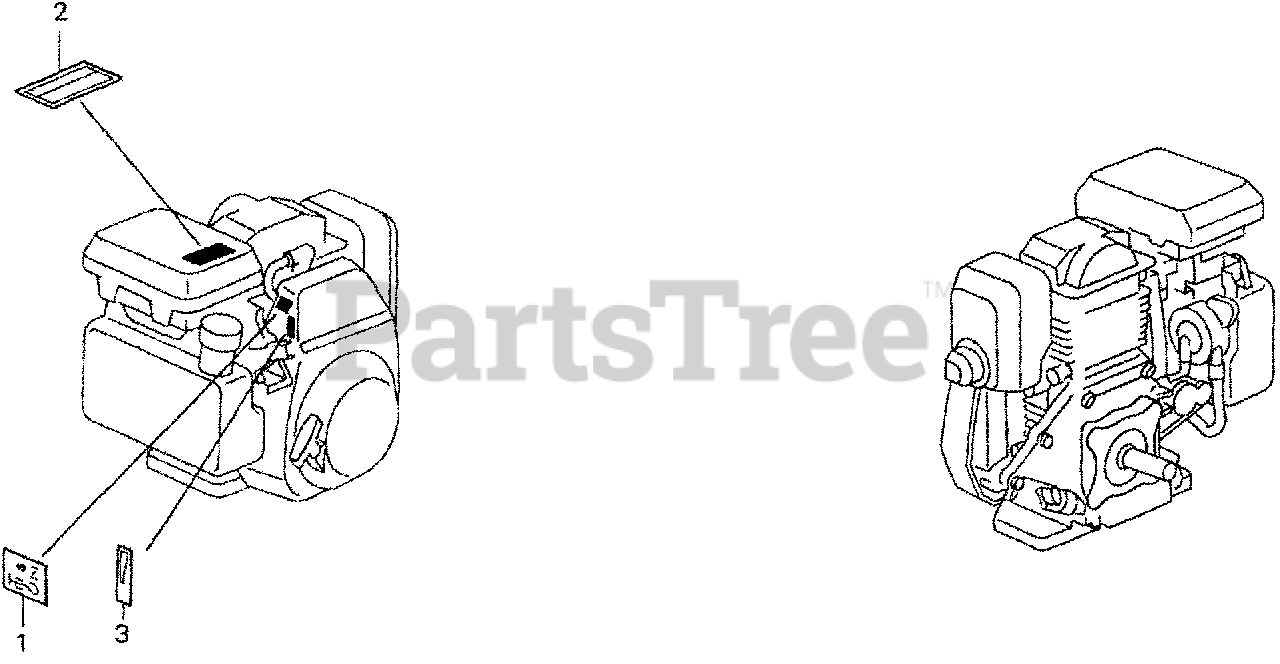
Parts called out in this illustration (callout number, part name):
1	MARK, CHOKE
2	MARK, OIL ALERT (E)
3	MARK, THROTTLE INDICATION
